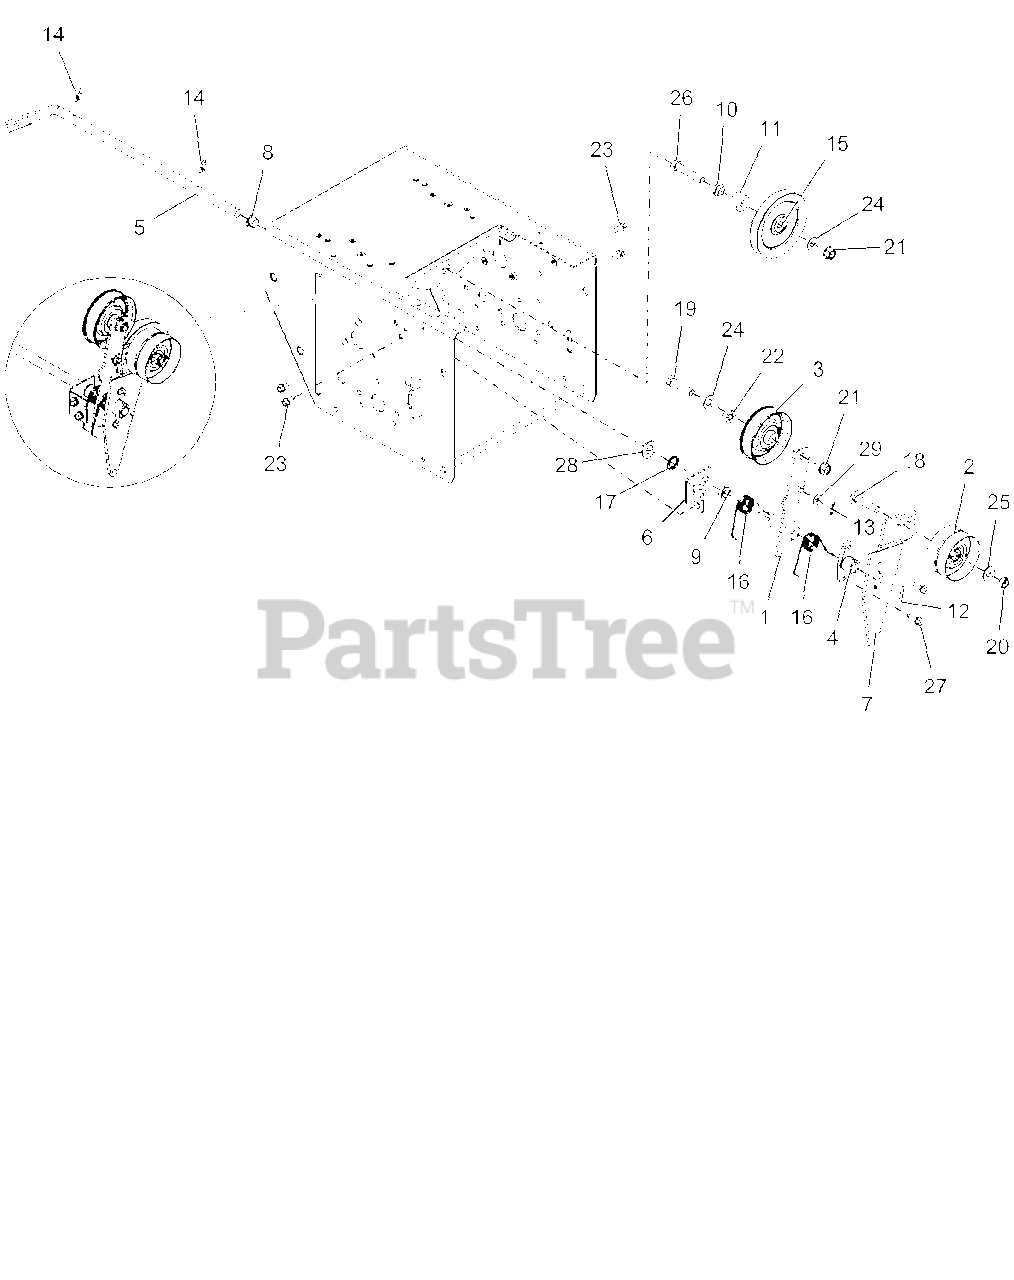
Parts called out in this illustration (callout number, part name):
1	ARM, TRACTION CLUTCH
2	IDLER, FLAT-2.75 OD X .375 ID
3	IDLER, FLAT - 3.05" X .75"
4	HUB, BRAKE ARM
5	ARM, ATTACHMENT
6	BRACKET, SUPPORT
7	ARM, IDLER-ATTACHMENT
8	BUSHING, POLYLINER-.50 SPLIT
9	BSHG,FLANGE .500X.625X.270X.75
10	BSHG, FLANGE .391X.56X.313X.75
11	BSHG,POCKET .391X.570X1.0X.450
12	PIN-ROLL .125X1.00
13	PIN-HAIR INT .06X.18X.77
14	CLIP, SPRING
15	SHV, .38"ID X 4.00"OD V-IDLER
16	SG-TORS .067X.88
17	WAVE SPRING .600X.875X.25FH
18	@BLT-RHDSSQNK .38-16X1.75 G5YZ
19	@BLT-HEX .38-16X1.50 GR5 YWZC
20	@NUT-LK-CTR-JAM .375-16 YWZC
21	@NUT-LK-TOP-FLG .38-16 YWZC
22	SPCR, BRG .315X.500X.358X.281
23	SCR-TAP .25-20X.50 HWH TR YWZ
24	@WSHR-FL-STL.406X.812X.065 YWZ
25	@WSHR-FL-STL.38X.875X.083 YWZC
26	@BLT-HEX .38-16X2.00 GR5 YWZC
27	SCR-TAP-PM .25-20X.75 TR YWZ
28	@WSHR-FL-STL.531X1.06X.095YWZC
29	@WSHR-FL-STL.281X.62X.065 YWZC
